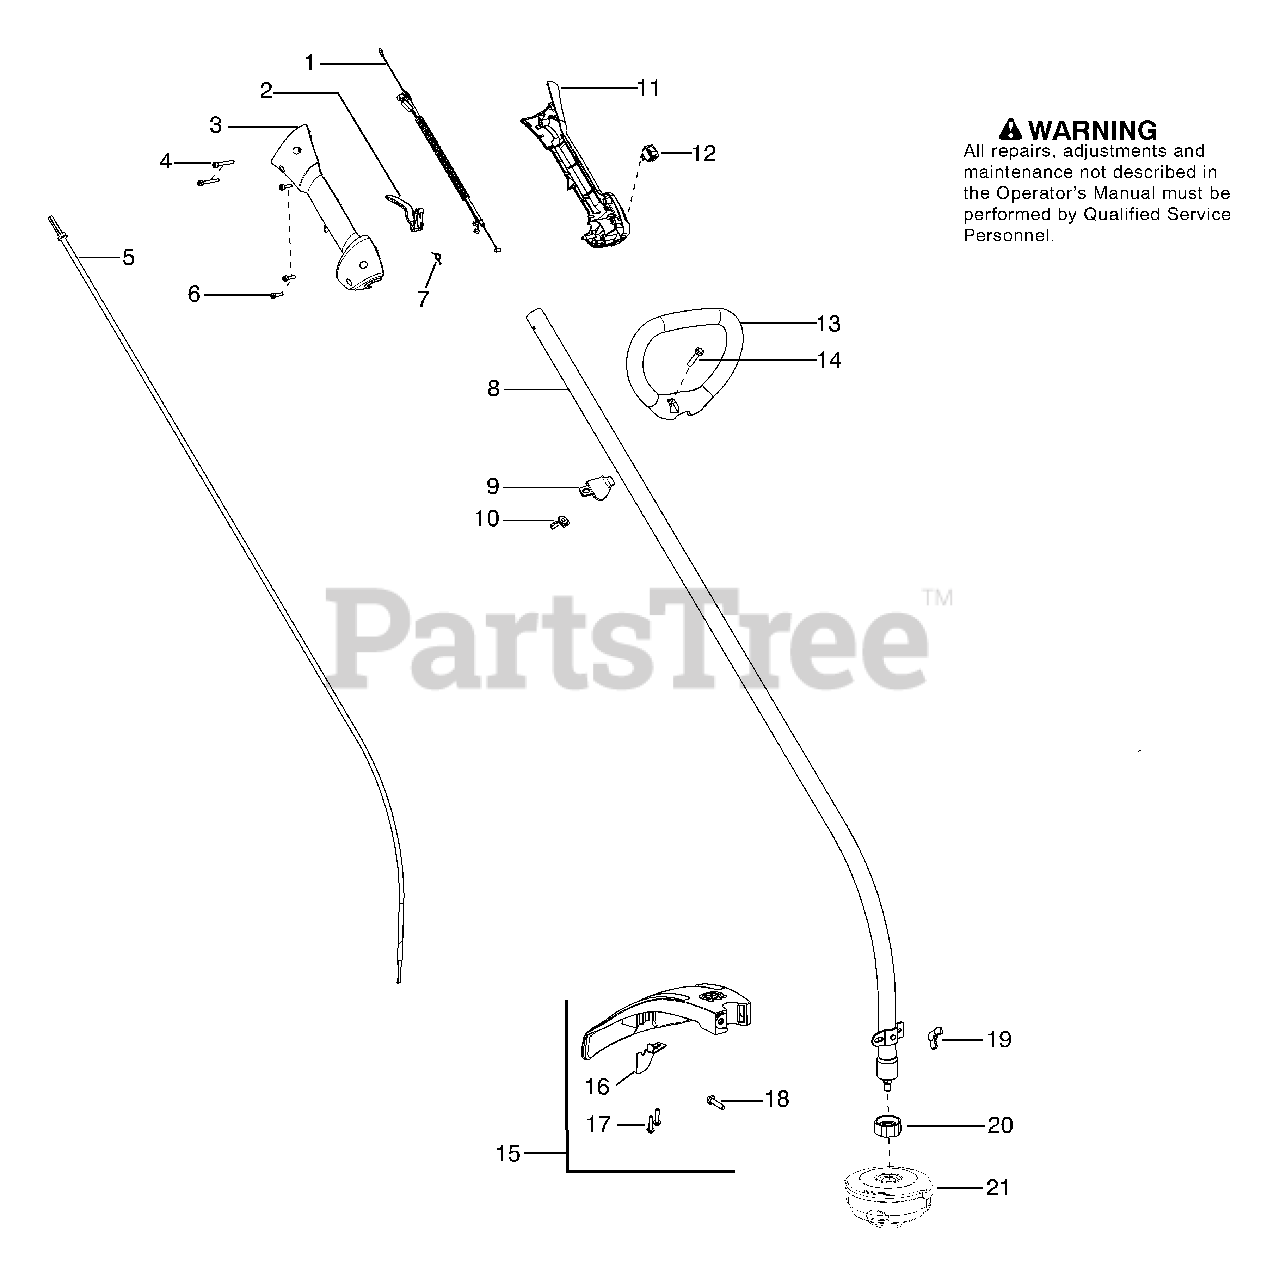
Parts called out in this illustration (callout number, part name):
1	Assy-Cable/Wire Harness
2	Trigger
3	Housing-Throttle (RH)
7	Spring-Trigger
8	Kit-Driveshaft
9	Clamp-Handle
10	Wingnut
11	Housing-Throttle (LH)
12	Kit-Switch
13	Handle-Assist
15	Kit-Shield
16	Limiter-Line
19	Wingnut
20	Dust Cup
21	Assy-T25 Cutting Head
